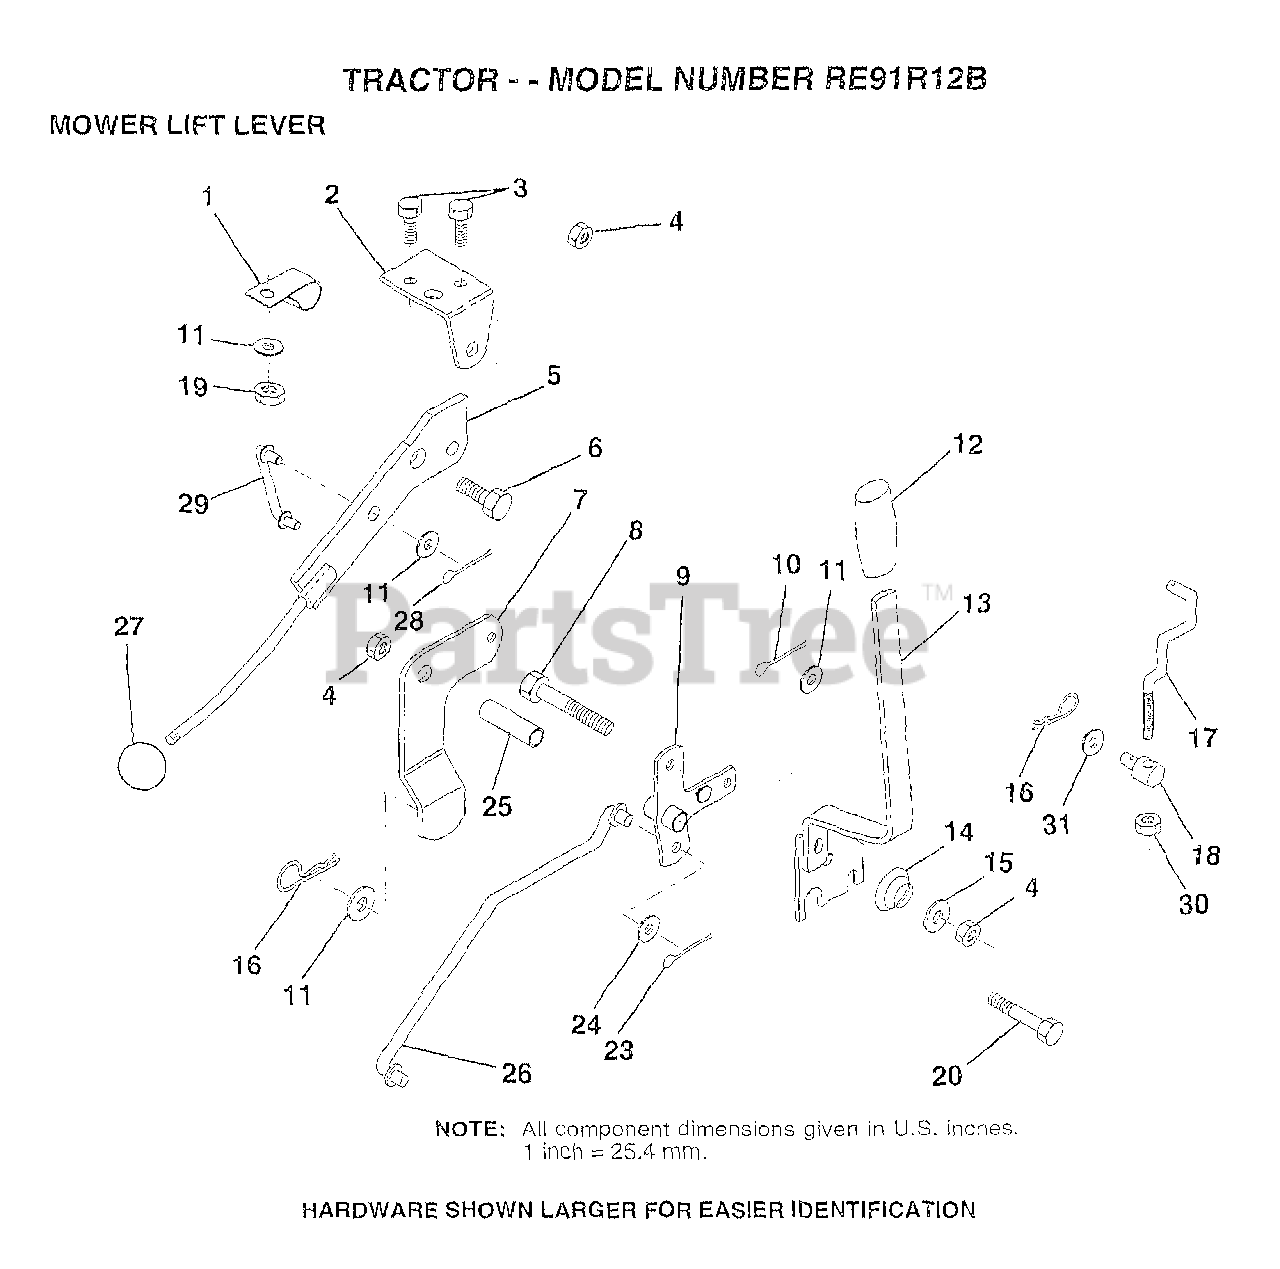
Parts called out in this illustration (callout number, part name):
1	"CLIP,INSULATOR"
2	BRKT CLUTCH
3	BOLT HXHD FIN
5	LEVER.ASM.CLUTCH
6	"BOLT, SHOULDER LT"
7	MWR CLUTCH ARM AS
8	BOLT
9	"BELLCRANK,LIFT"
10	COTTER PIN
11	WASHER
13	HANDLE.ASM.LIFT
14	SPRING COMPRESSIO
15	WASHER T
17	"LINK,LIFT FRT"
18	TRUNION ADJ
20	BOLT
23	PIN COTTER 1/8
25	TUBE SPACER
26	ROD LIFT MOWER
27	KNOB T(3/8 HOLE)
29	CLUTCH LINK
30	NUT
31	WASHER
